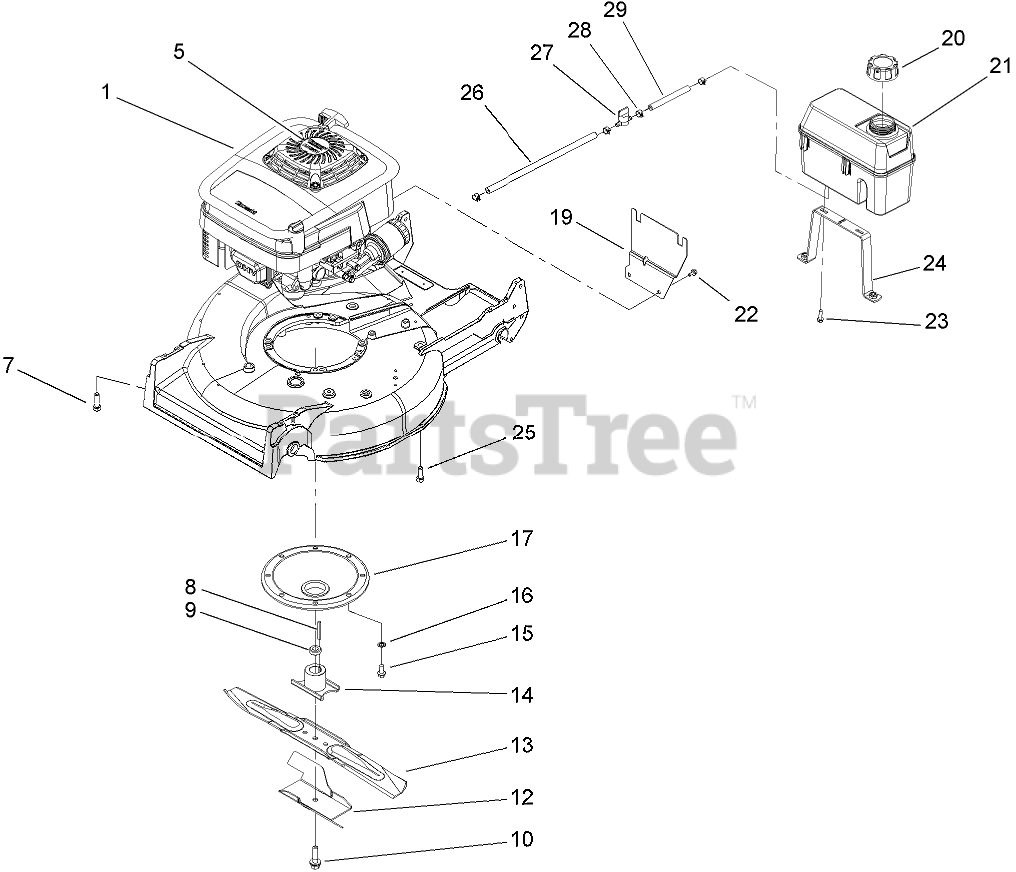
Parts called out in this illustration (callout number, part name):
1	ENGINE-KAWASAKI, FJ180V-CS10S
5	DECAL-RECOIL
7	SCREW-TAPTITE
8	KEY-SQUARE
9	Spacer-Retainer, Blade
10	BOLT-BLADE
12	STIFFENER-BLADE
13	BLADE-21 INCH
14	RETAINER-BLADE
15	SCREW-HWHTF
16	WASHER-LOCK, INTERNAL
17	PROTECTOR-CRANKSHAFT
19	BRACKET-TANK
20	CAP-GAS
21	Tank-Fuel
22	SCREW-HWH
23	SCREW-HWH
24	TANK BASE
25	SCREW-TAPTITE
26	HOSE-FUEL
27	VALVE-FUEL
28	CLAMP-HOSE
29	HOSE-GAS
